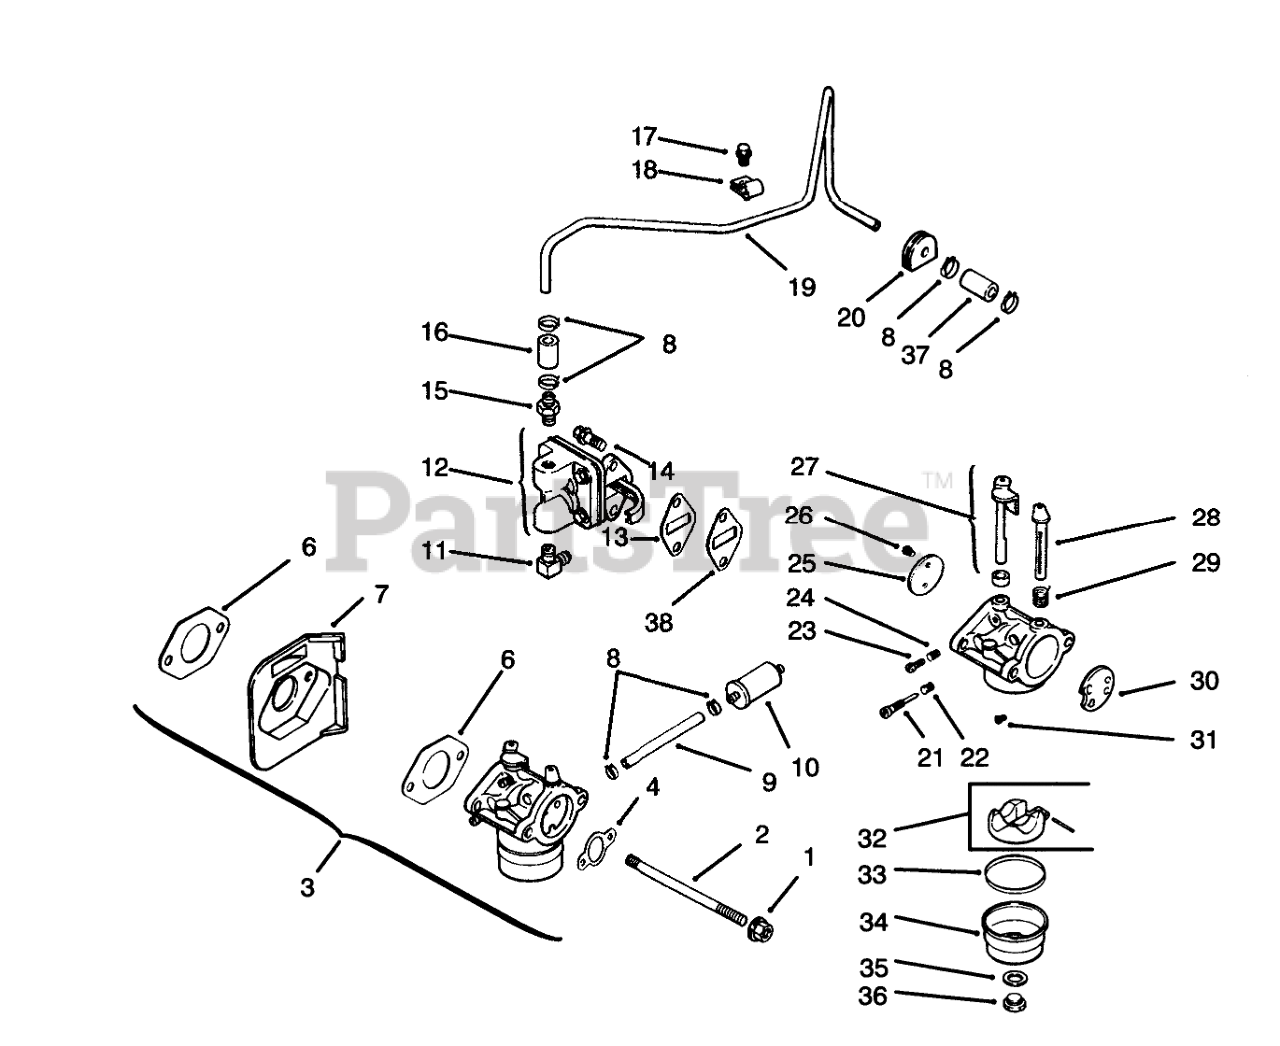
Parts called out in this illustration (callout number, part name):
2	Stud
4	Gasket
5	Carurator ASM Incl 21-36
6	Gasket
7	Deflector-Heat
8	Clamp
9	Line-Fuel
10	Filter-Fuel
11	Connector-90deg.
12	Kit-Pump INC 13-14
13	Gasket-Fuel Pump
14	Screw
15	Connector
16	Line-Fuel 1.25 Inch
18	Clamp-Fuel Line
19	Line-Fuel
20	Grommet
21	Needle-Idle Fuel Adjust
22	Spring-Idle
23	Screw-Idle
24	Spring-Idle
25	Plate-Throttle
26	Screw-Throttle Plate
27	Shaft-Throttle
28	Shaft-Choke
29	Spring
30	Plate-Choke
31	Jet-Main
32	Kit-Float
33	Gasket-Bowl
34	Bowl
35	Gasket
36	Screw-Bowl
37	Line-Fuel
38	Spacer-Fuel Pump
